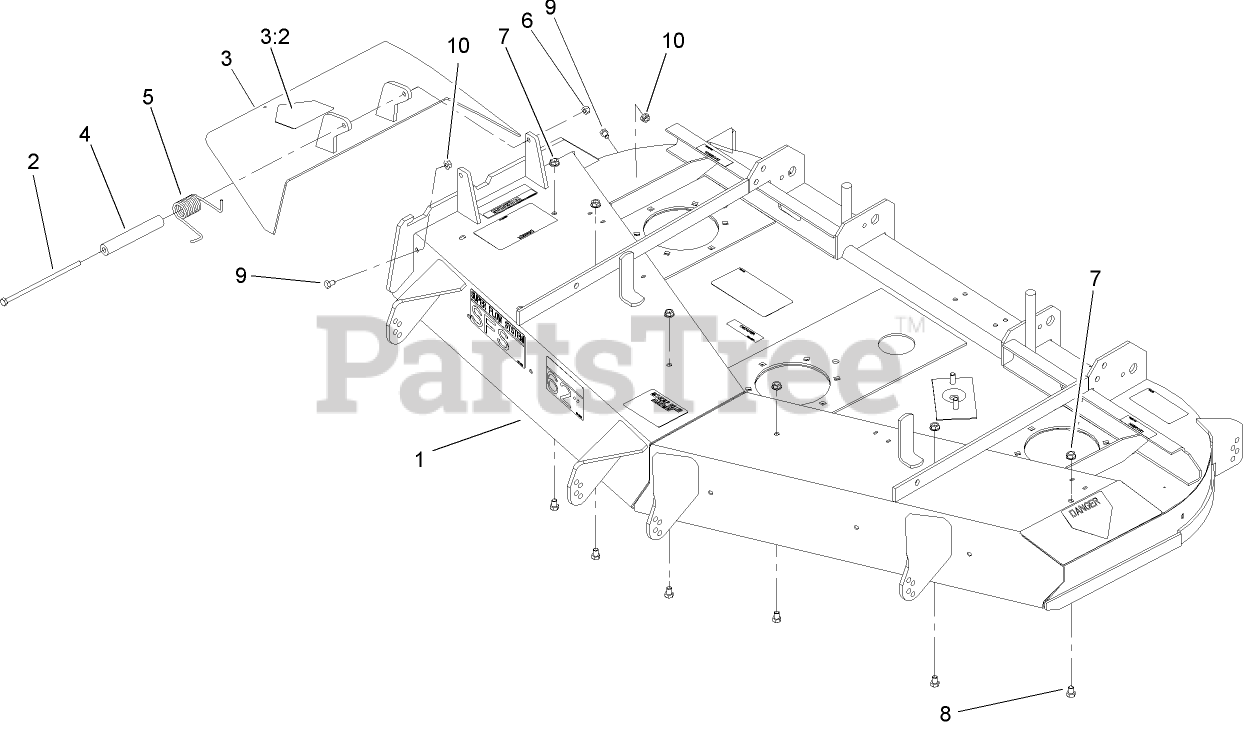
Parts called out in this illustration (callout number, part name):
1	Deck ASM
2	SCREW-HH
3	Deflector ASM
3:2	DECAL-DANGER
4	SPACER
5	SPRING-TORSION
6	NUT-LOCK, NI
7	NUT-HHF, WHIZ
8	SCREW-HH
9	SCREW-HH
10	NUT-HF
